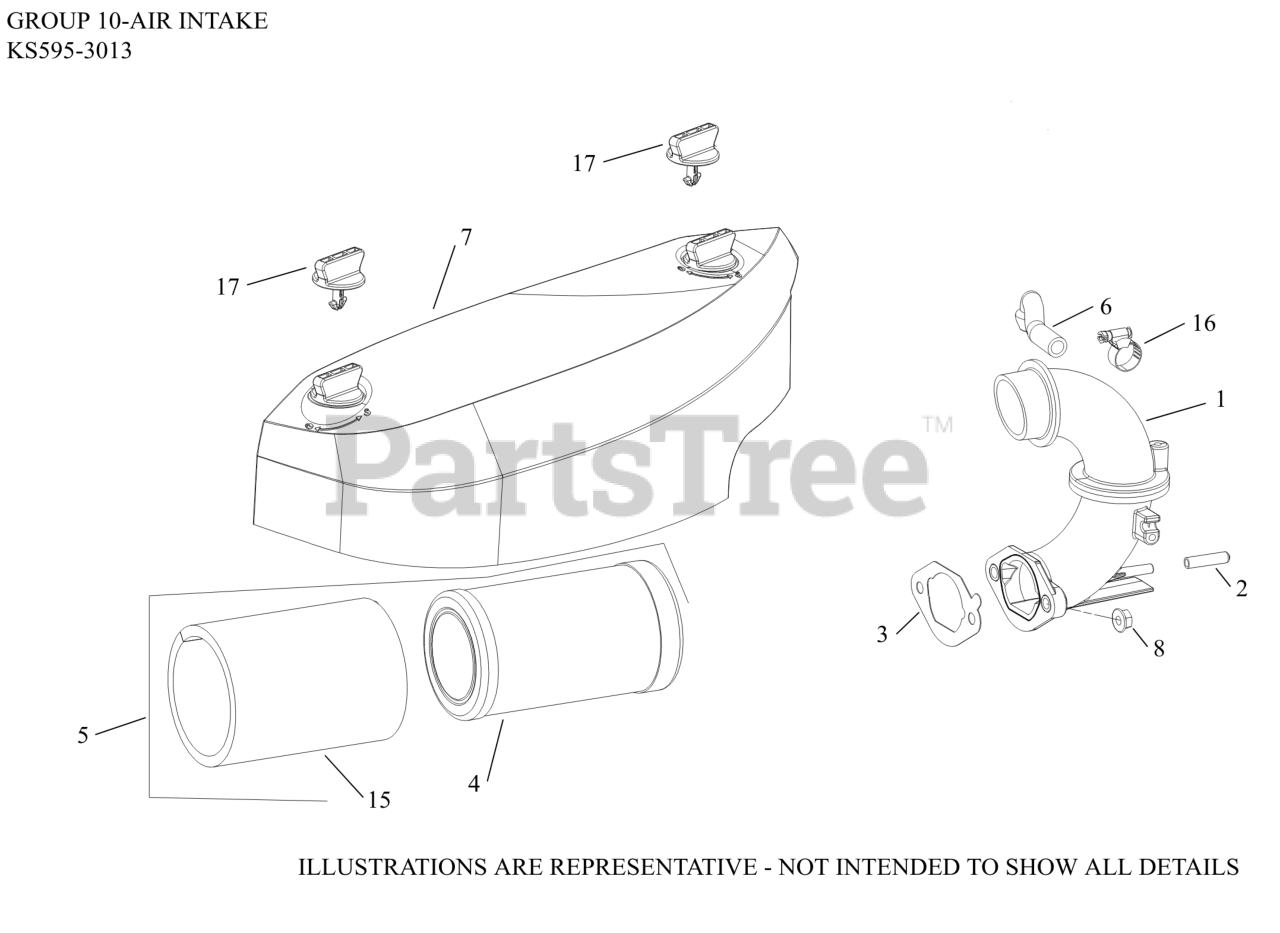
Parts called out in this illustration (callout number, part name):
1	ADAPTER, AIR CLEANER ASSY
2	CAP, MASKING
3	GASKET, CARBURETOR
4	ELEMENT, AIR FILTER
5	AIR FILTER KIT (STD)
6	HOSE, BREATHER
7	COVER, AIR CLEANER ASSY
8	NUT, FLG M6X1.0
15	ELEMENT, PRE-CLEANER
16	CLAMP, HOSE (KM)-USE 25 237 31-S
17	KNOB, AIR CLEANER COVER
